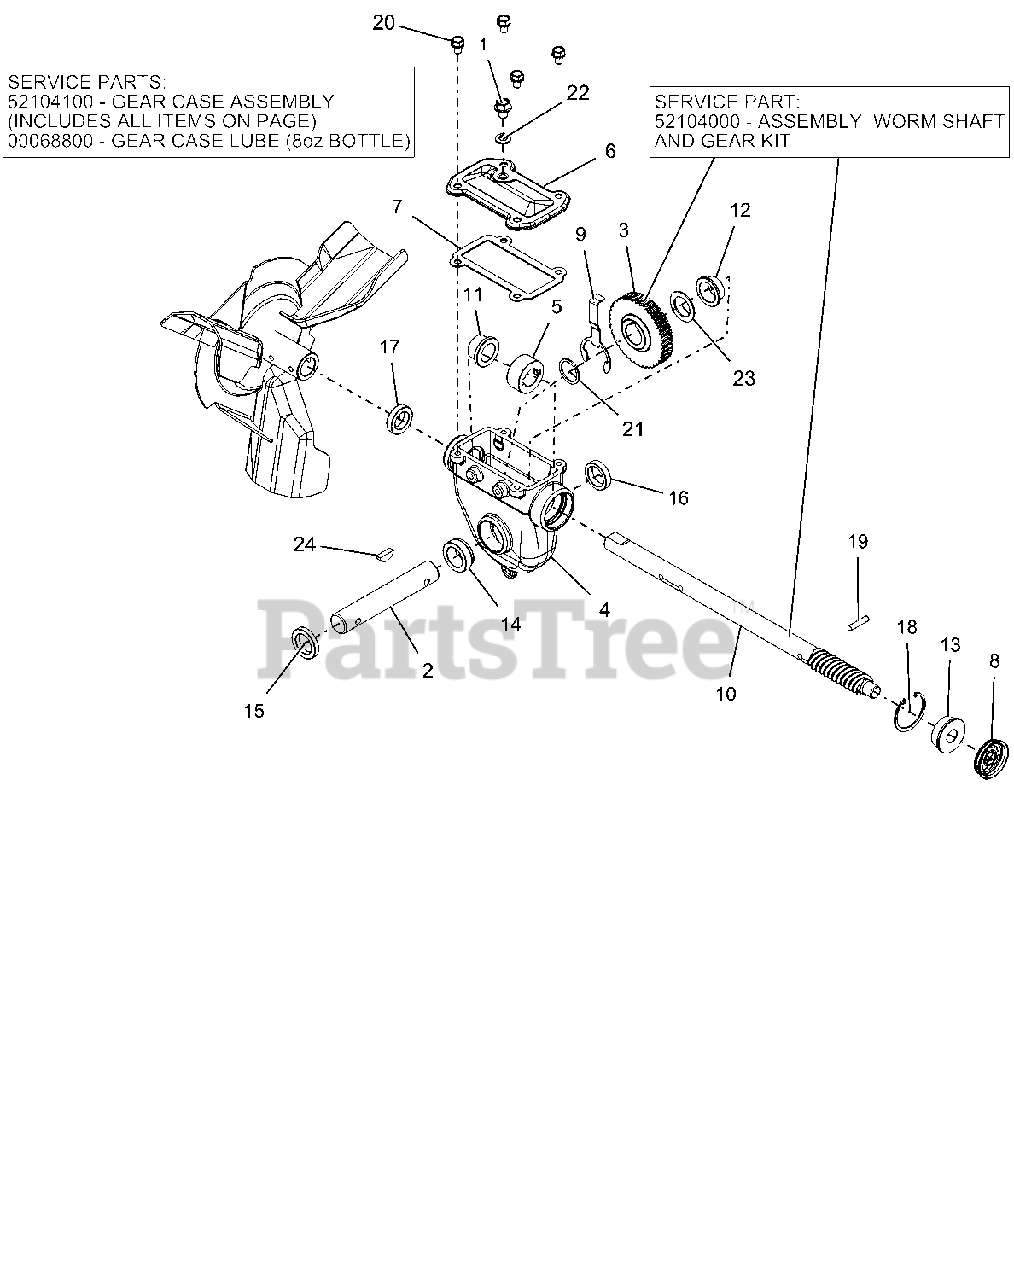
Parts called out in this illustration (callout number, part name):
1	@SCR-ROLOK .38-16X.50 HWH YWZC
2	RAKE SHAFT, SHORT-COMMON
3	WORM GEAR
4	GEARCASE, LARGE MACHINED
5	THRUST COLLAR, .875"ID SLIPFIT
6	COVER, TOP - LARGE IRON
7	GASKET, TOP - LARGE GEARCASE
8	COVER, GEAR CASE 1.75"
9	BUSHING RETAINER, LARGE
10	WORM SHAFT & GEAR
10	SHAFT, WORM - DELUXE
11	BSHG-FLG .879X1.128X.75X1.45
12	BSHG-FLG 1.006X1.128X.555X1.45
13	BSHG-FLG .628X1.503X.58X1.725
14	BSHG-FLG LARGE, RIGHT
15	SEAL-OIL .999X1.500X.250 TBC29
16	SEAL-OIL .999X1.375X.312 TBC29
17	SEAL-OIL .873X1.375X.312 TBC29
18	RG-RTNG-INT 1.750X.062
19	PIN-STR .250X1.12 6150
20	BOLT, SEMS .31-18X.50 GR5 YWZC
21	WSHR-FL-STL 1.010X1.250X.068YZ
22	WSHR-BND-SEAL .38X.75X.11 GALV
23	WSHR-FL-STL 1.010X1.505X.062YZ
24	KEY-WDRF .25X.875 HRD #A
25	GEAR CASE ASSY - DLX IRON
26	ARIENS L3 LUBE, 8 OZ BOTTLE
